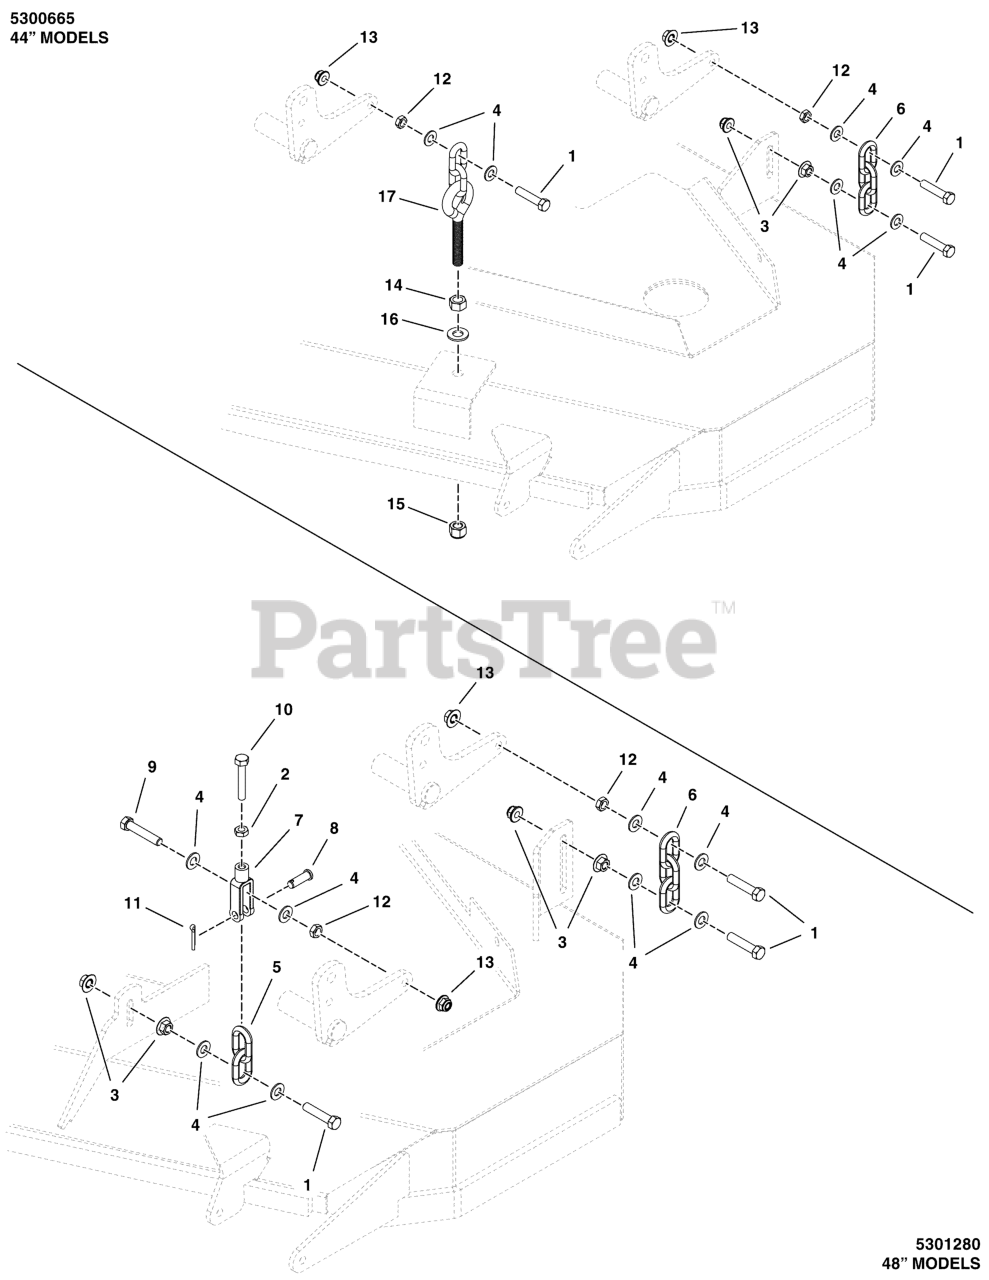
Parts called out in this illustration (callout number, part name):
1	BOLT, 3/8-16 X 1-3/4" GD5 CZ
2	NUT, 5/16-18 HEX JAM
3	NUT, 3/8-16 HEX SERRATED FLANGE
4	WASHER, 3/8 SAE
5	CHAIN, 5/16 GD30, 2 LINKS
6	CHAIN, 5/16 GD30, 3 LINKS
7	CLEVIS, 5/16-18, 3/8 PIN HOLE, CLR ZINC
8	PIN, CLEVIS, 3/8 X 1-1/8, CZ
9	BOLT, 3/8-16 X 2, GD5, CZ
10	BOLT, 5/16-18 X 2 GD5 TFL
11	PIN, COTTER, 1/8 X 3/4
12	NUT, 3/8-16 HEX JAM
13	NUT, 3/8-16 HEX NYLOCK FLANGE
14	NUT, 1/2-13 HEX, YZ
15	NUT, 1/2-13 HEX NYLON LOCK
16	WASHER, 1/2 SAE
17	HANGER, FRONT DECK-2LINK, 5.5" EB
